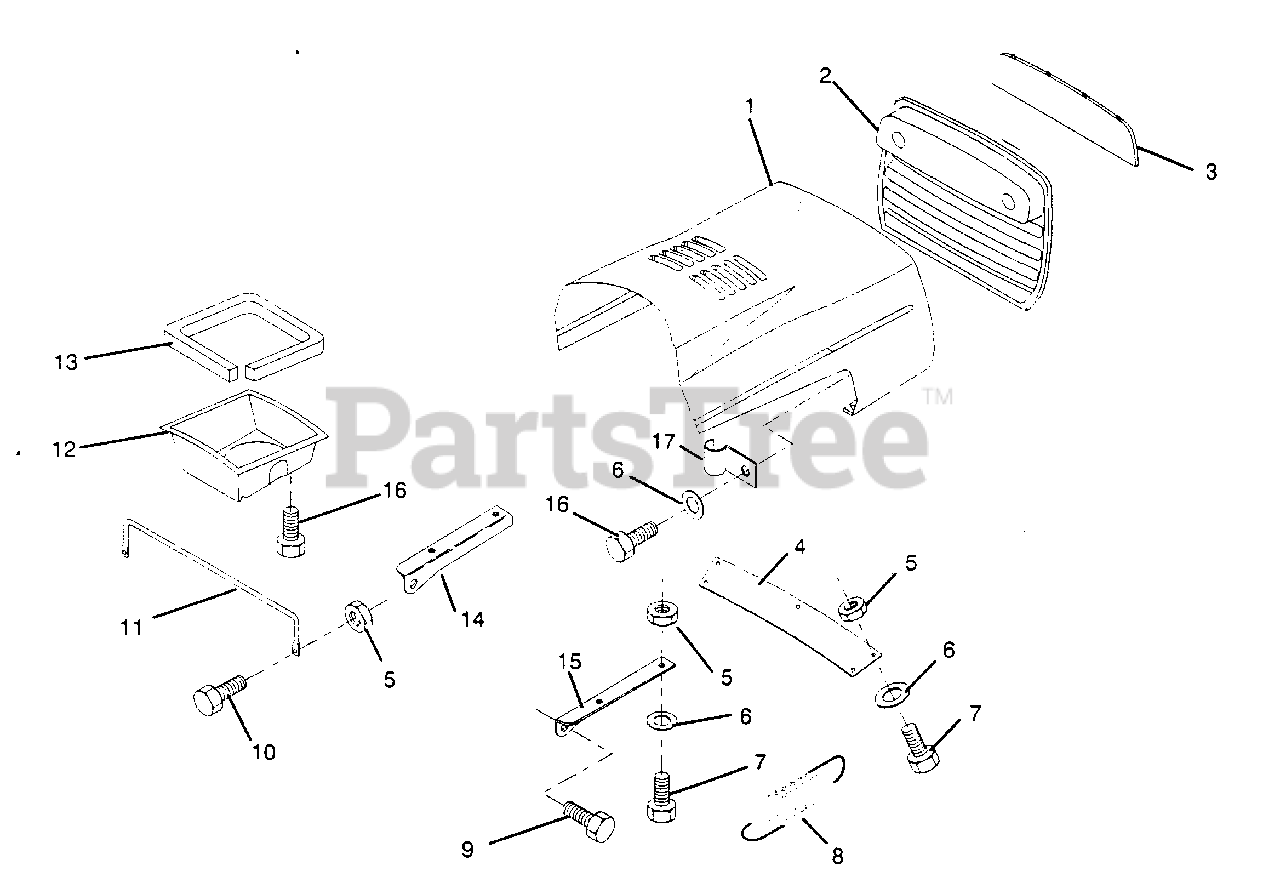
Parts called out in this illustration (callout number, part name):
2	Grill
5	Nut, Hex Keps 1/4-20 UNC
6	Washer, 9/32 x 5/8 x 16 Ga.
7	Bolt, Hex Fin. 1/4-20 UNC x 5/8 Gr. 5
8	Extension, Spring
9	Bolt, Thrd. Forming Shoulder
10	Bolt, Hex Fin. 1/4-20 x 3/4 Gr. 5
14	Bracket, Hood L.H.
15	Bracket, Hood R.H.
16	Screw, Fin. Hex #13-16 Hi-Lo x 5/8
17	Clip, Fuel Line
